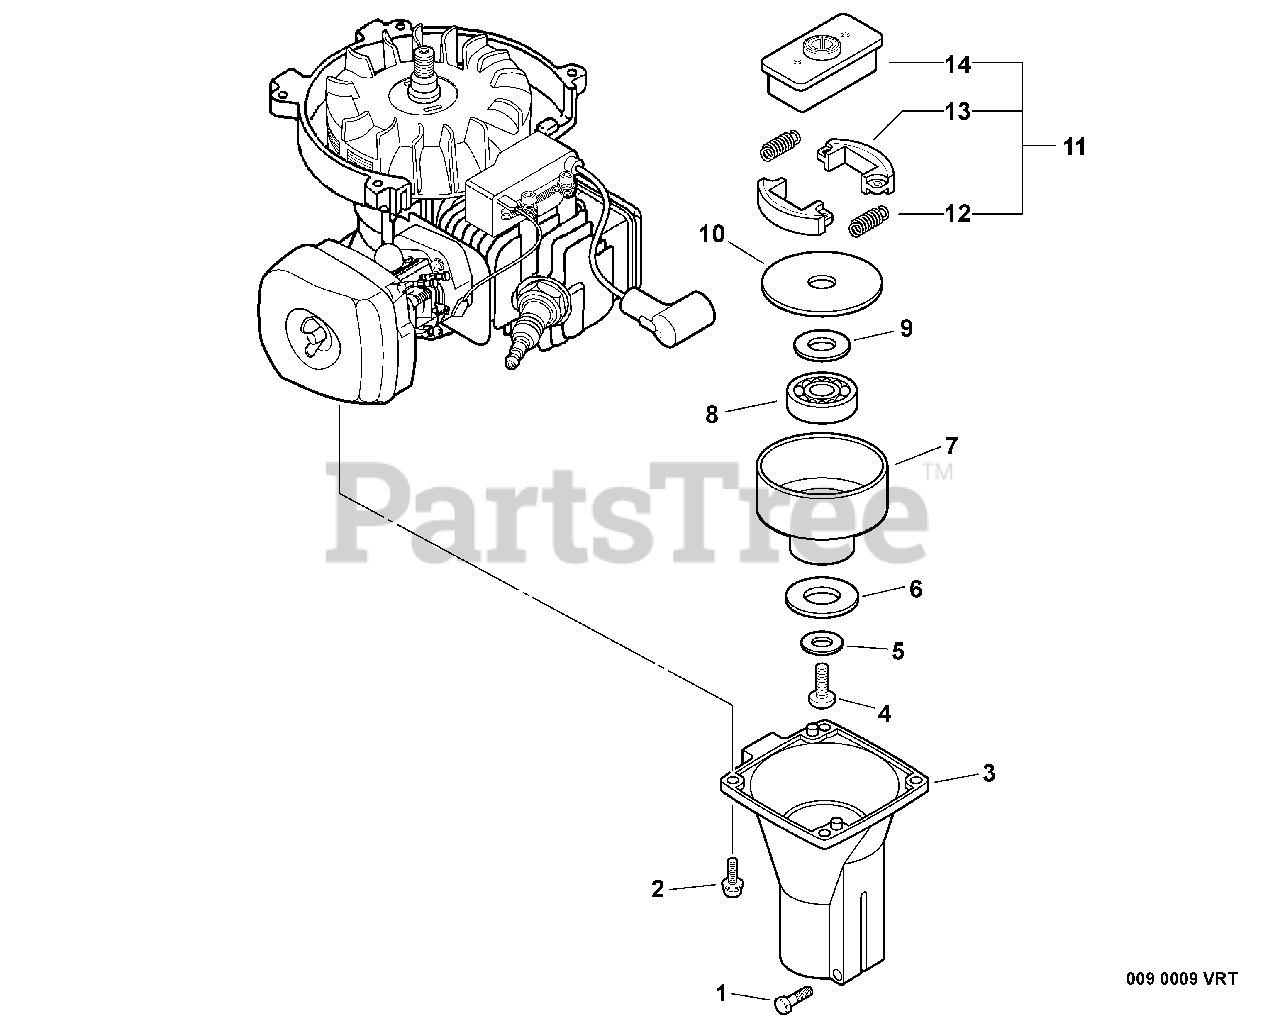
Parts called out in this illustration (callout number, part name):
1	BOLT 5
2	SCREW 4×14
3	CASE, CLUTCH
4	SCREW 6×12
5	WASHER, CLUTCH
7	DRUM, CLUTCH
8	BEARING, BALL 6000-2RLB
9	WASHER 10.5×18×1.6
10	PLATE, CLUTCH
11	CLUTCH ASSY
12	SPRING, CLUTCH
13	SHOE, CLUTCH
14	HUB, CLUTCH
